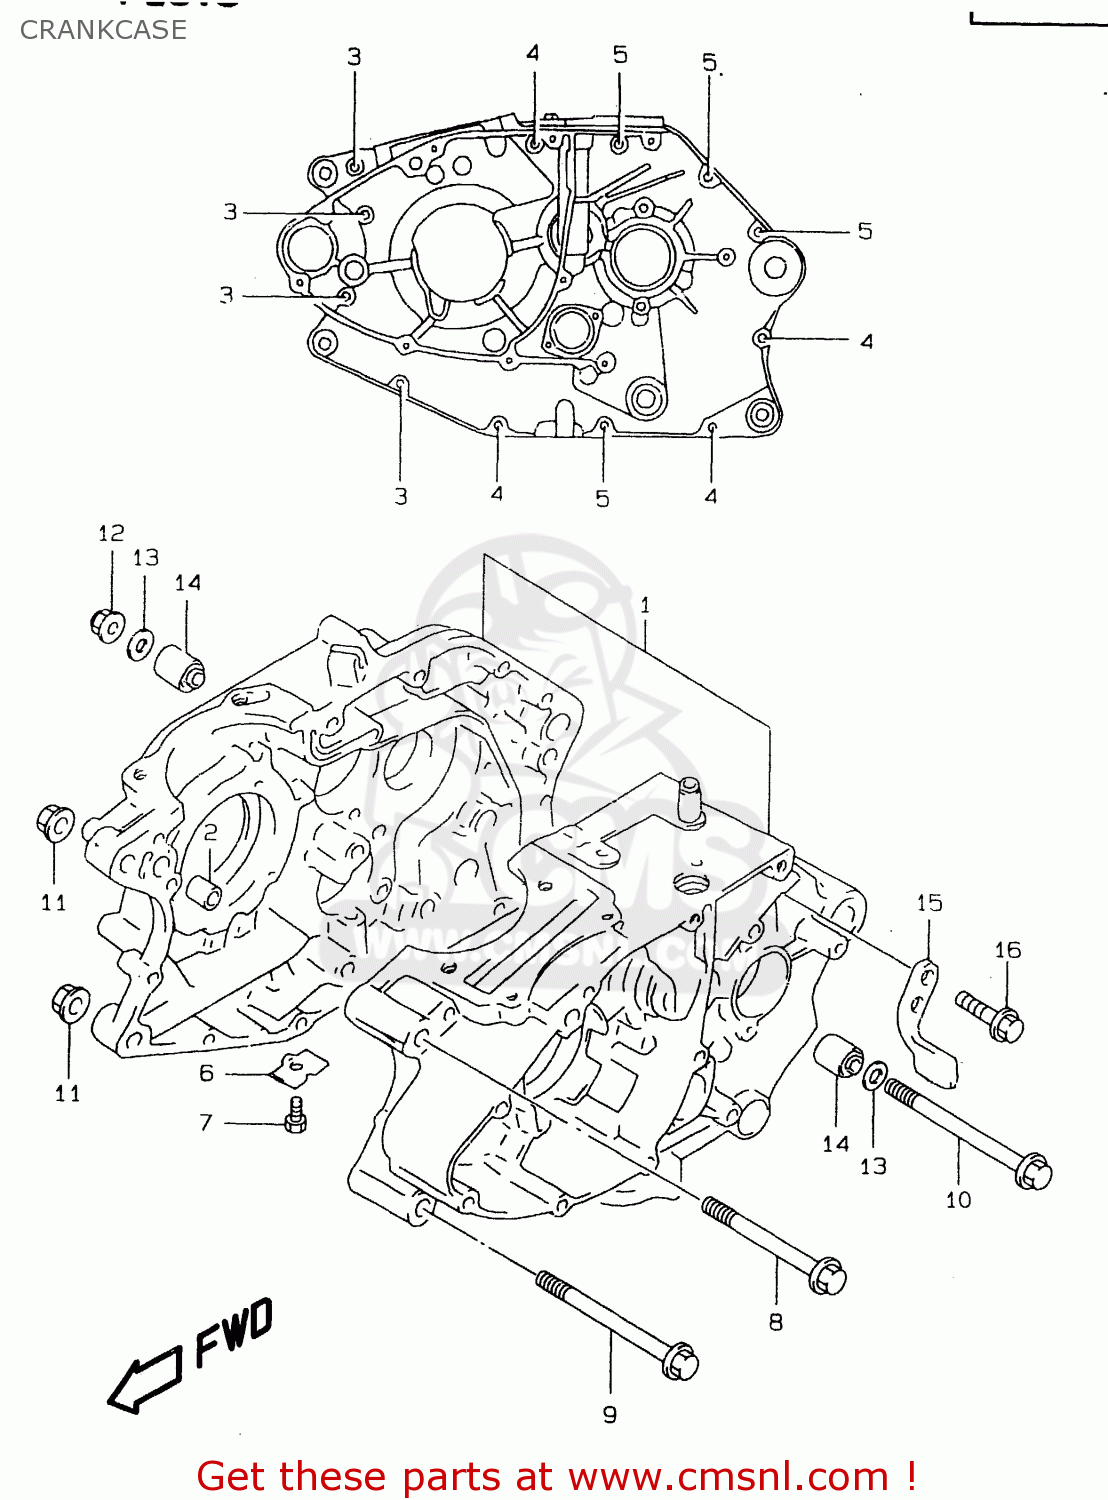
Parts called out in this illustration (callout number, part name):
1	CRANKCASE ASSY
2	PIN
3	BOLT
4	BOLT
5	BOLT
6	PLATE,OIL GALLERY PLUG
7	BOLT
8	BOLT(10X80)
9	BOLT(10X90)
10	BOLT(8X115)
11	NUT
12	NUT
13	WASHER
14	BUSH(8.4X18X16)
15	LIMITER,ENGINE SPROCKET
16	SCREW(6X18)
